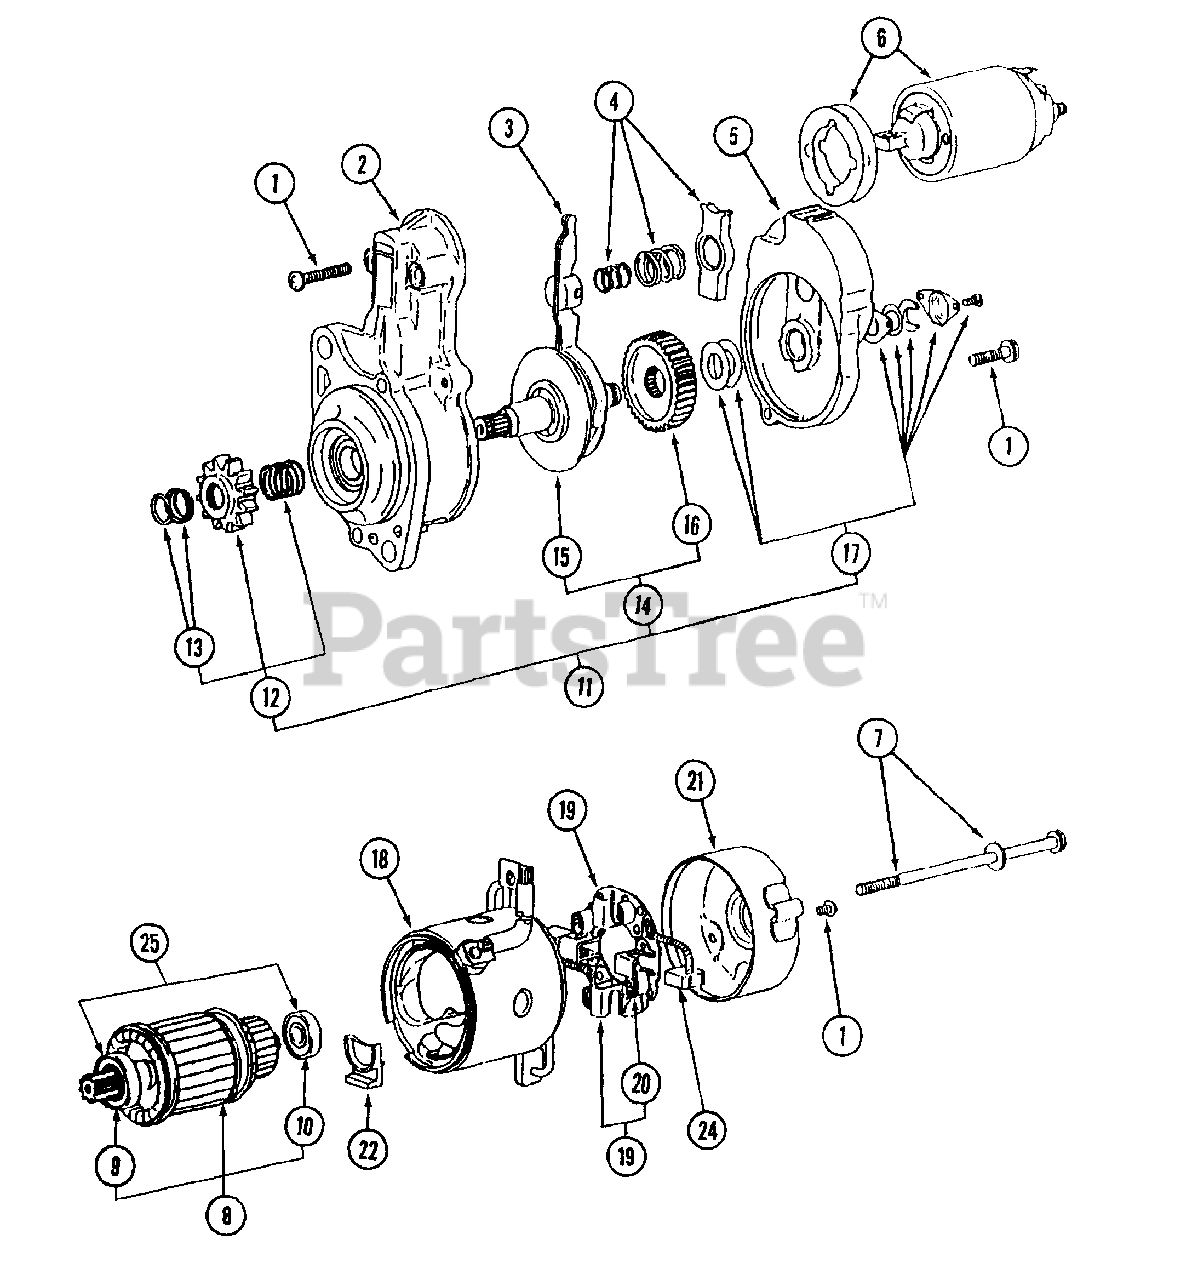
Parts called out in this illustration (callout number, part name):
2	Bracket Ass'y., Front
3	Lever Ass'y.
4	Spring Set
5	Bracket Ass'y., Center
6	Switch Ass'y.
8	Armature Set
9	Bearing, Front
10	Bearing, Rear
11	Shaft Ass'y., Clutch Set
15	Shaft Ass'y., Pinion
19	Holder Ass'y., Brush
20	Spring, Brush
21	Bracket Ass'y., Rear
24	Brush
25	Service Kit
